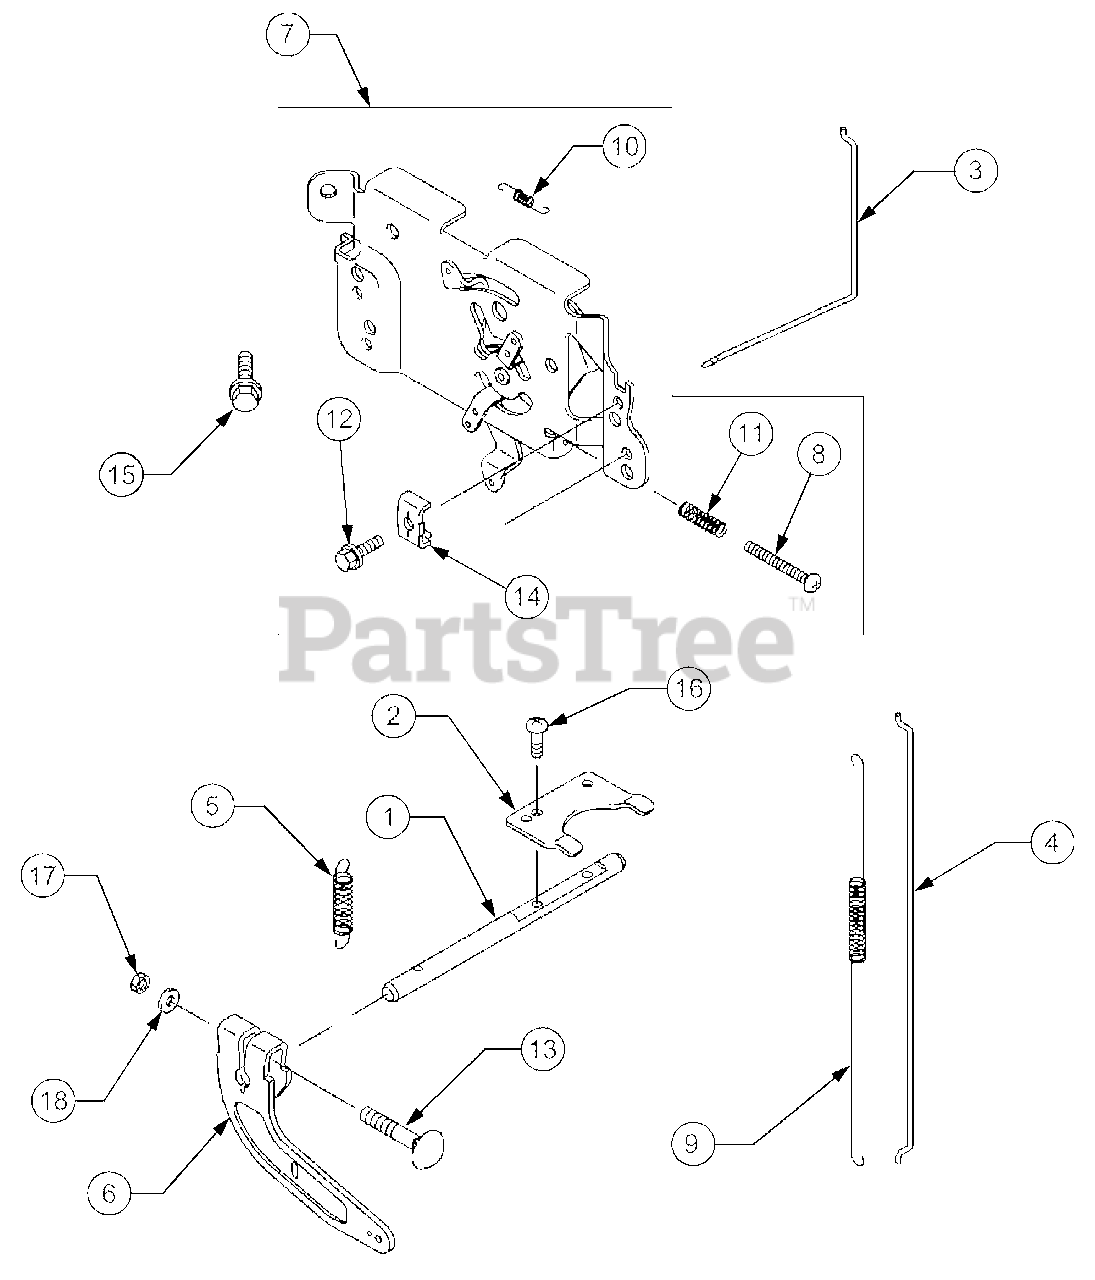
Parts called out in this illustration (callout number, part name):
2	Plate
5	Spring, Governor
6	Arm, Governor
7	Panel Comp, Control
10	Spring
13	Bolt, 6x35
15	Bolt, Flanged
16	Screw, Pan
17	Nut, Hex
18	Washer, Plain
